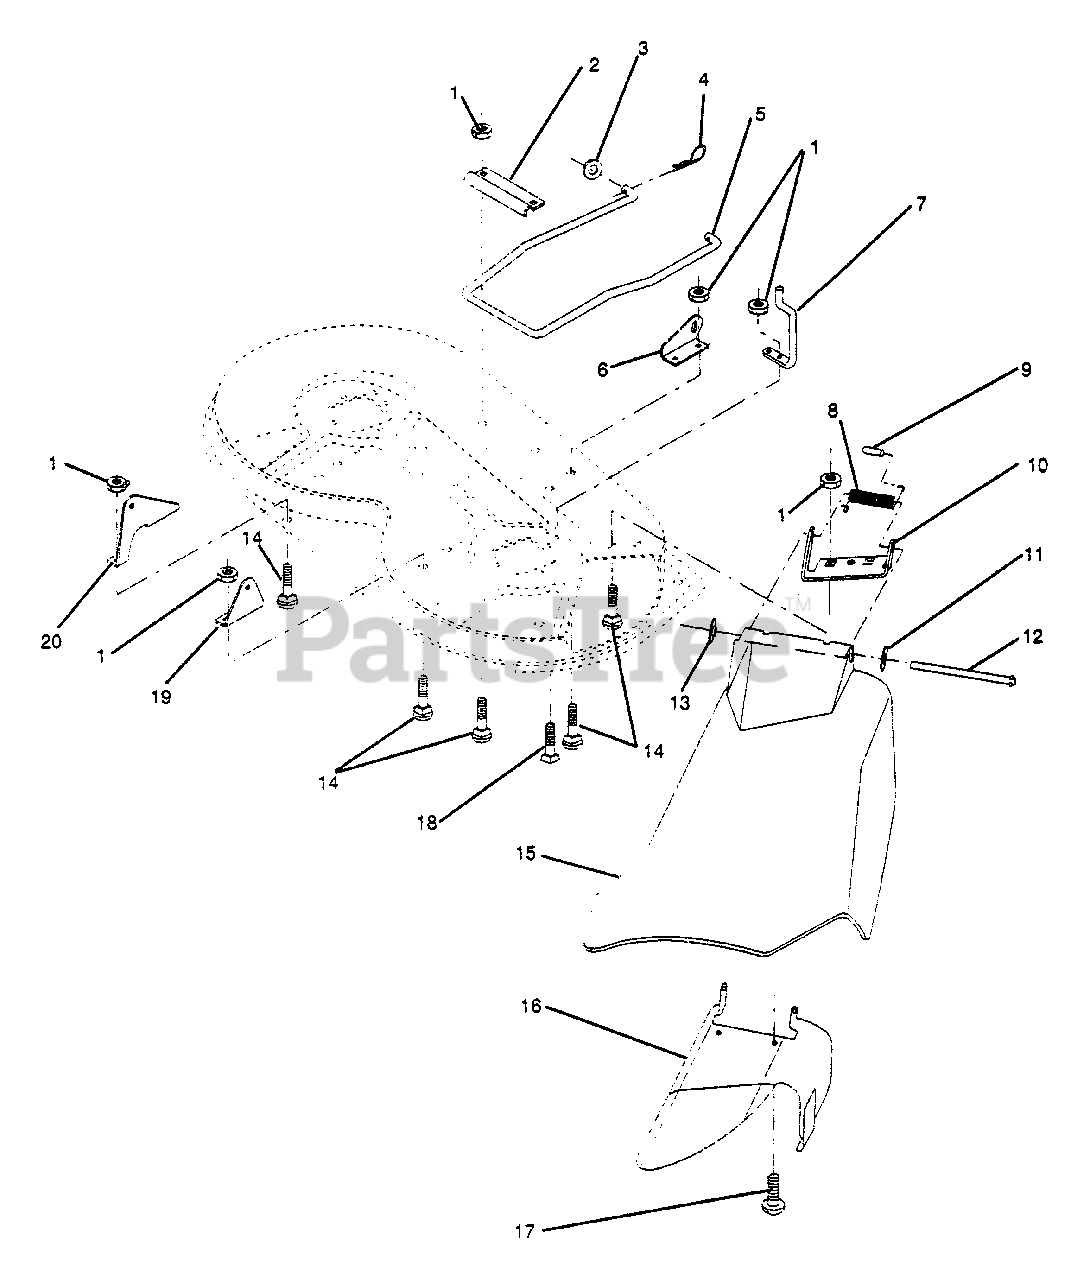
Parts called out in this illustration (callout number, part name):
1	Nut, Crownlock 5/16-18
2	Bracket, Stabilizer Link
3	Washer 17/32 x 1-1/16 x 13 Ga.
4	Clip, Hairpin
5	Stabilizer, Mower Link
6	Bracket, R.H. Front Lift
7	Guide, Front Mandrel R.H. Mower Belt
8	Spring, Torsion
9	Cap, Sleeve
10	Bracket, Deflector
11	Washer 11/32 x 5/8 Ga.
12	Rod, Hinge
14	Bolt, Carriage 5/16-18 UNC x 5/8
15	Guard, Discharge
16	Assembly, Deflector Support
17	Screw, Pan Hd. PLT-30
18	Bolt, Hex Head 5/16-18 UNC x 3/4
19	Bracket, R.H. Rear Lift
20	Bracket, LH. Rear Lift
